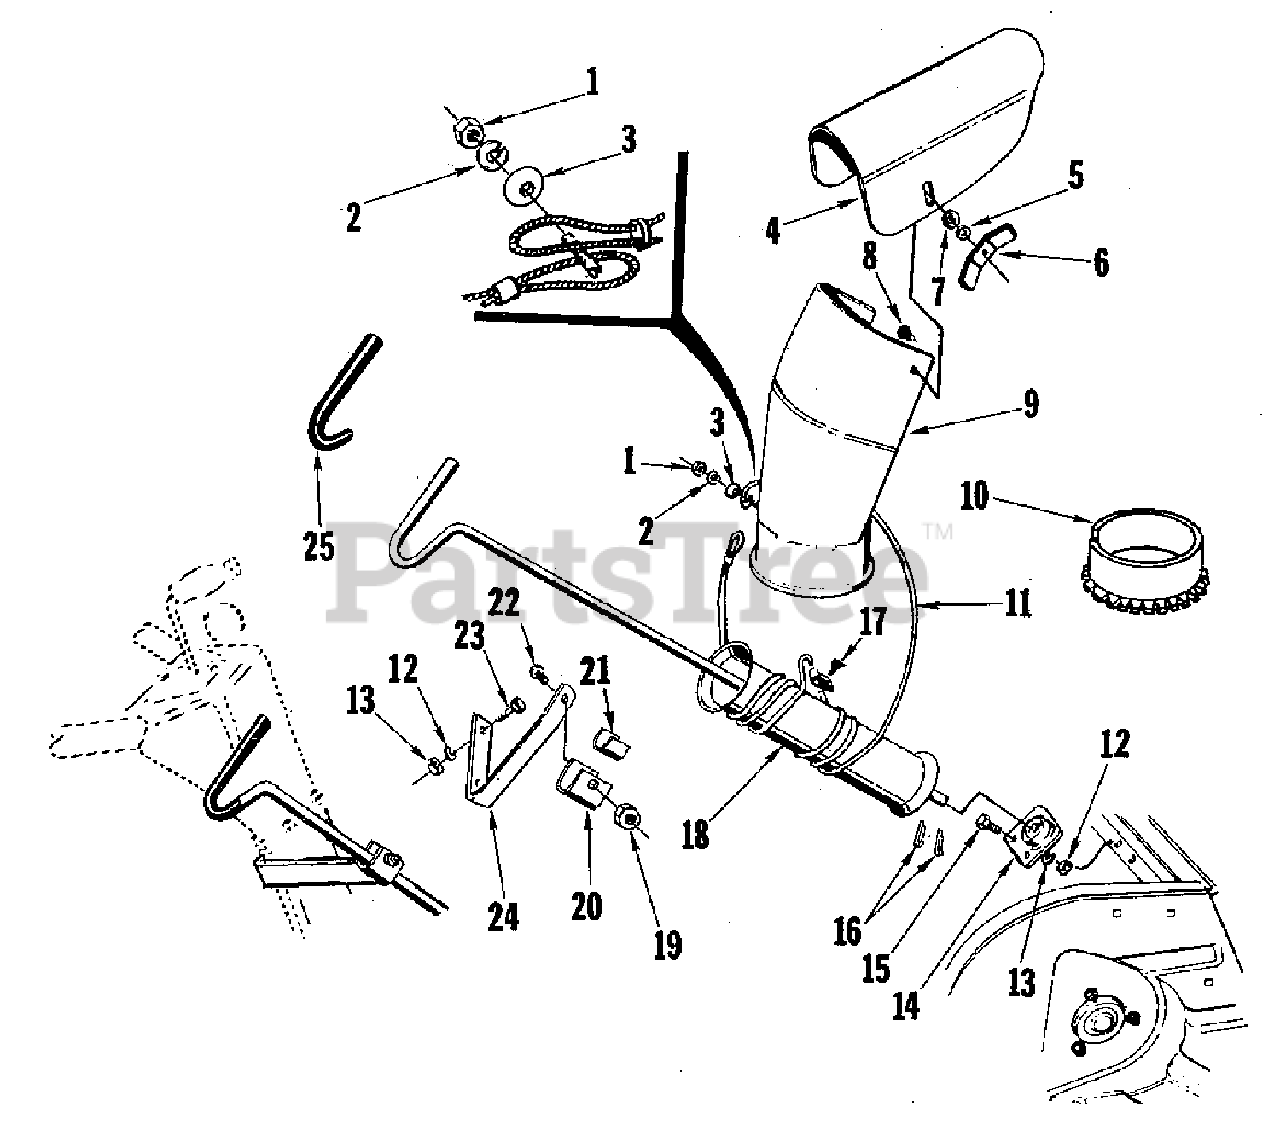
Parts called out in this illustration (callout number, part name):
1	NUT, Hex, 5/16-18
2	WASHER, Lock, 5/16"
4	EXTENSION, Spout
5	WASHER, Flat, 3/
7	WASHER, Lock, Shakeproof 3/8
8	BOLT, Carriage, 5/16-18 x 3/4
9	SPOUT ASSEMBLY
11	CABLE ASSEMBLY
12	NUT, Hex, 1/4-20
13	WASHER, Lock, 1/4
15	SCREW, Cap Hex Head, 1/4-20 x 5/8
16	PIN, Cotter, 3/32 x 5/8
17	SCREW, Taptite, 1/4-20 x 3/8
18	TUBE ASSEMBLY, Spout Control
19	NUT, Lock Hex, 5/16-18
21	LINER, Guide
22	SCREW, Cap Hex Head, 5/16-18 x 1-1/4
23	SCREW, Cap Hex Head, 1/4-20 x 1-3/4
24	SUPPORT, Spout Adjustment Rod
25	HANDLE, Grip
